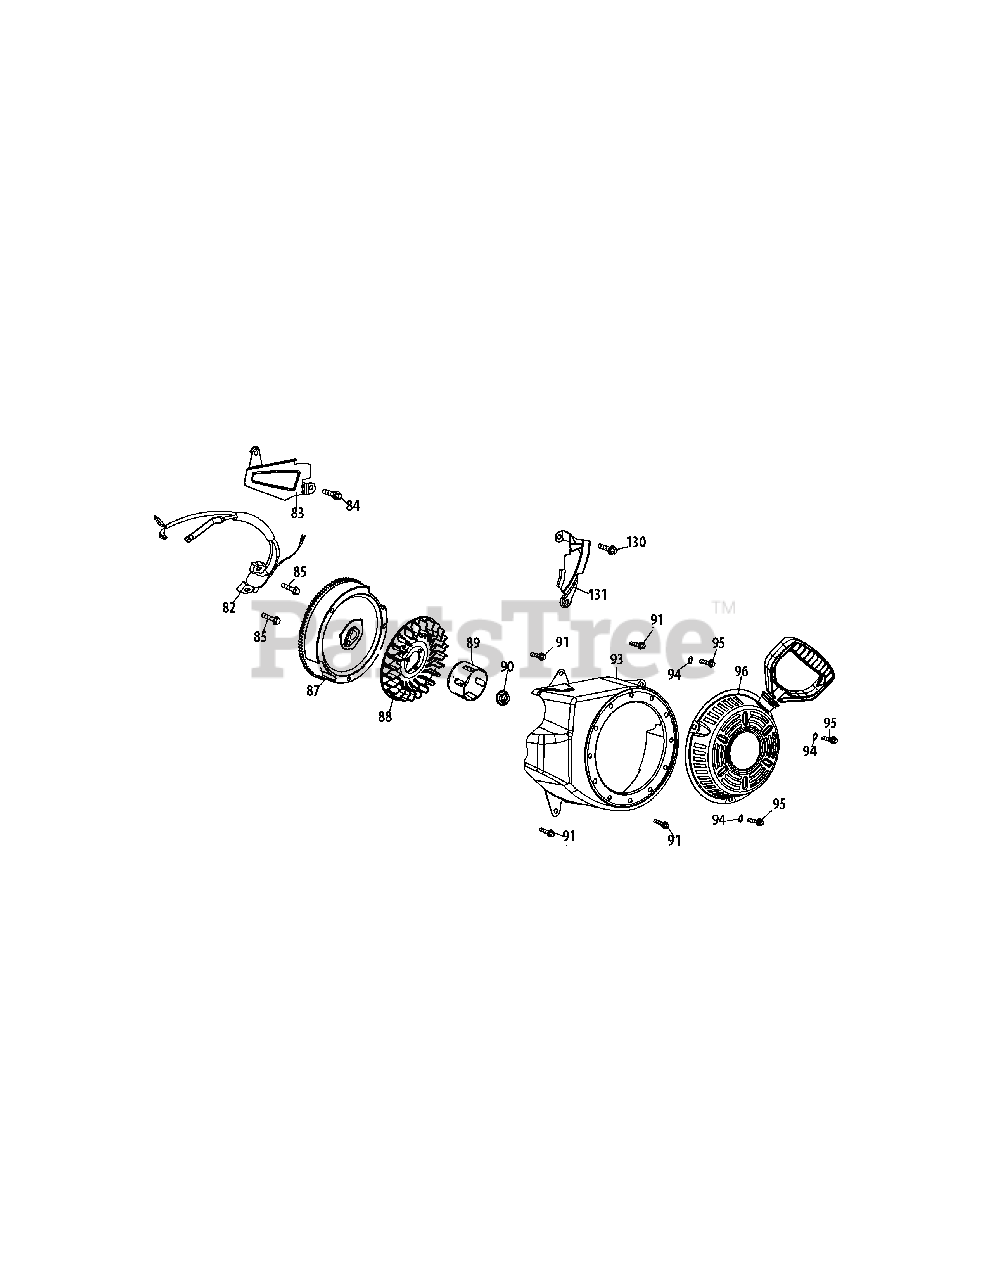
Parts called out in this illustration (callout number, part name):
82	Ignition Coil Assembly
83	Air Flow Shield
84	Bolt M6×10
85	Bolt M6×25
87	Flywheel
88	Fan, Cooling
89	Pulley, Starter
90	Nut, Special M14×1.5
91	Bolt M6×12
93	Blower Housing
94	Gasket 6
95	Bolt M6×10
96	Recoil Starter
96	Recoil Starter Handle
130	Bolt M6×18
131	Blower Housing Shield
